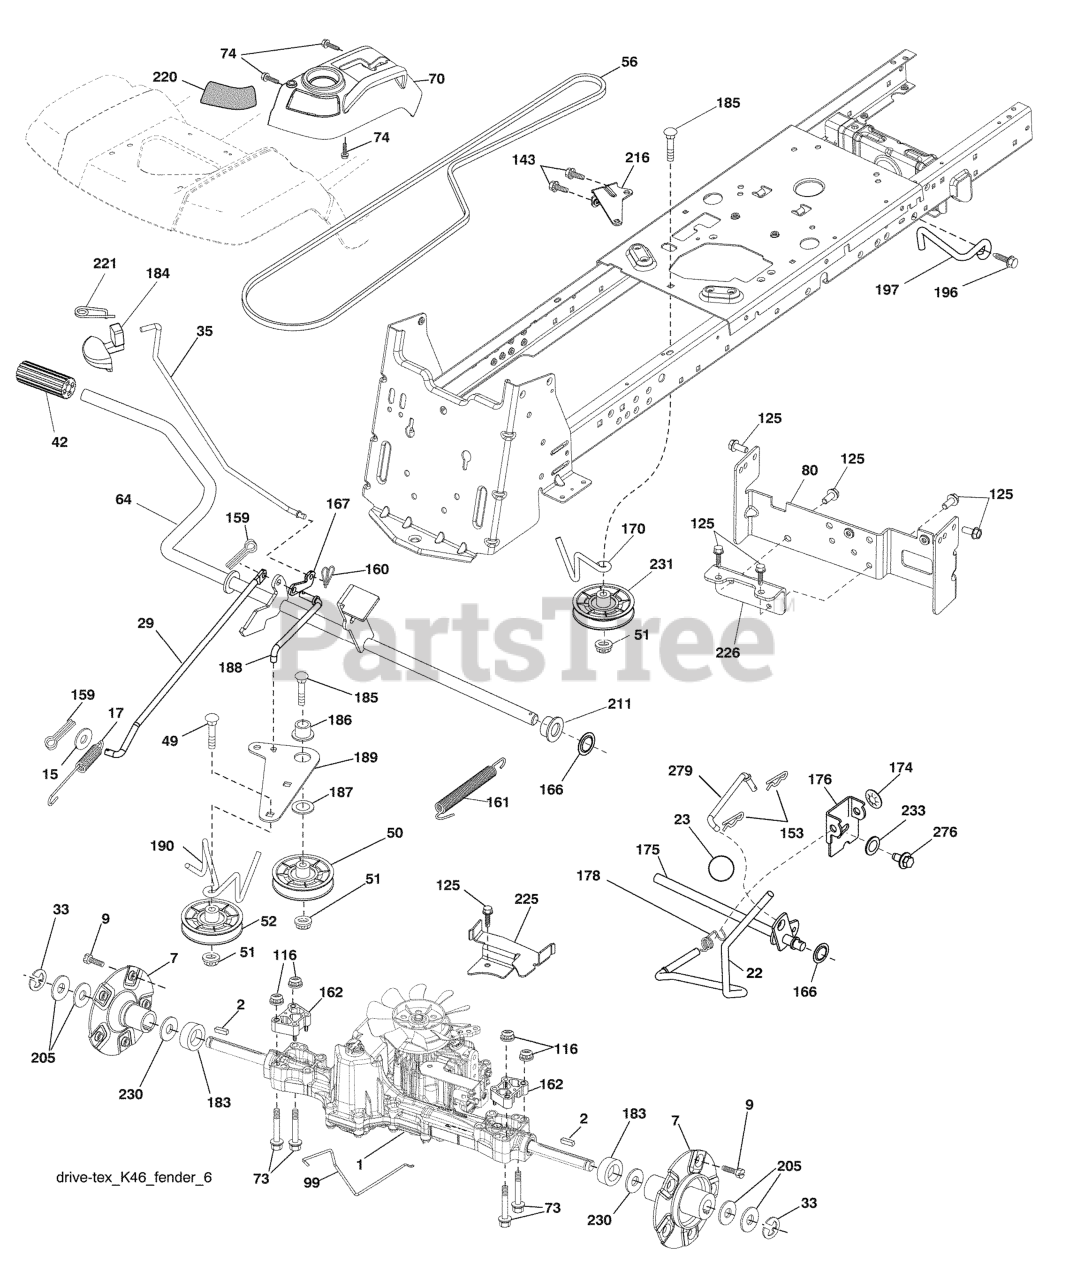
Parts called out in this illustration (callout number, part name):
1	TRANSAXLE(K46AW)22"FS
2	KEY.SQUARE.187X2.500
7	HUB.ASM.WHEEL.REAR.22"
9	HUB BOLT
15	WASHER
17	SPRING.BRAKE.K46.GREEN
22	ROD.SHIFT.FENDER.STGT.
23	KNOB.DELUXE.(PISTOL.GRIP).BLAC
29	ROD.BRAKE.K46
35	ROD.BRAKE.PARKING.GT.H
42	PEDAL COVER T
49	BOLT
50	IDLER.FLAT.910.OFFSET
51	NUT LOCK FLG 3/8-16 UNC
52	IDLER.V-GROOVE.910.OFFSET
56	V-BELT.MOWER.92.40.42/K46
64	SHAFT.ASM.PEDAL.BRAKE.
70	RP CONSOLE.ASM.HYDO.HUSQ.
73	BOLT HEX 5/16-18 GR 5
74	SCREW.HI-LO.CONSOLE
80	STRAP TORQUE
99	ROD.SPRING.BYPASS.K46.TEX.GT
116	NUT LOCK HEX FLANGE 5/16-18
125	SCREW
143	Screw 5/16-18 x 1/2
153	RETAINER M
159	COTTER PIN
160	RETAINER CLIP
161	SPRING, RETURN LT
162	SPACER.TRANSAXLE.18&22
166	NUT.PUSH.625.2006
167	LATCH.BRAKE.SPRING
170	KEEPER.CENTER SPAN.1.688
174	NUT.PUSH.500.2006
175	SHAFT ASM SHIFT
176	ARM.CLEVIS.ROD.SHIFT
178	SPRING.SHIFT.GT2006
183	SPACER.SPLIT.800X.350
184	HANDLE.PARKG.BRK.HUSQ X667
186	SPACER.RETAINER
187	WASHER 12/32X2X10GA
188	RP.LINK.CLUTCH.GROUND.DRIVE
189	BELLCRANK.GROUND.DRIVE.TEX.
190	KEEPER.BELLCRANK.DRIVE
196	SCREW 3/8-16X1
197	BRKT.ANIT-ROTATION.CLUTCH
211	BUSHING.SHAFT.BRAKE.HAND
216	BRACKET.PULLEY.IDLER.W/TEX
220	REFLECTOR.RH.TEX GT
221	RETAINER.SPRING.CLIP.H
225	KEEPER.BELT.TRANSAXLE.K46
226	BRKT.MOUNT.TORQUE.K46.
230	WASHER.HARDENED
231	IDLER.V-GROOVE.1.688.OFFSET
233	WASHER SERRATED
276	BOLT FIN HEX 7/16-14 X 1
279	LINK.SHIFT.T/A.K46.FEND.TX
282	SPACER.SPLIT.800X.350
